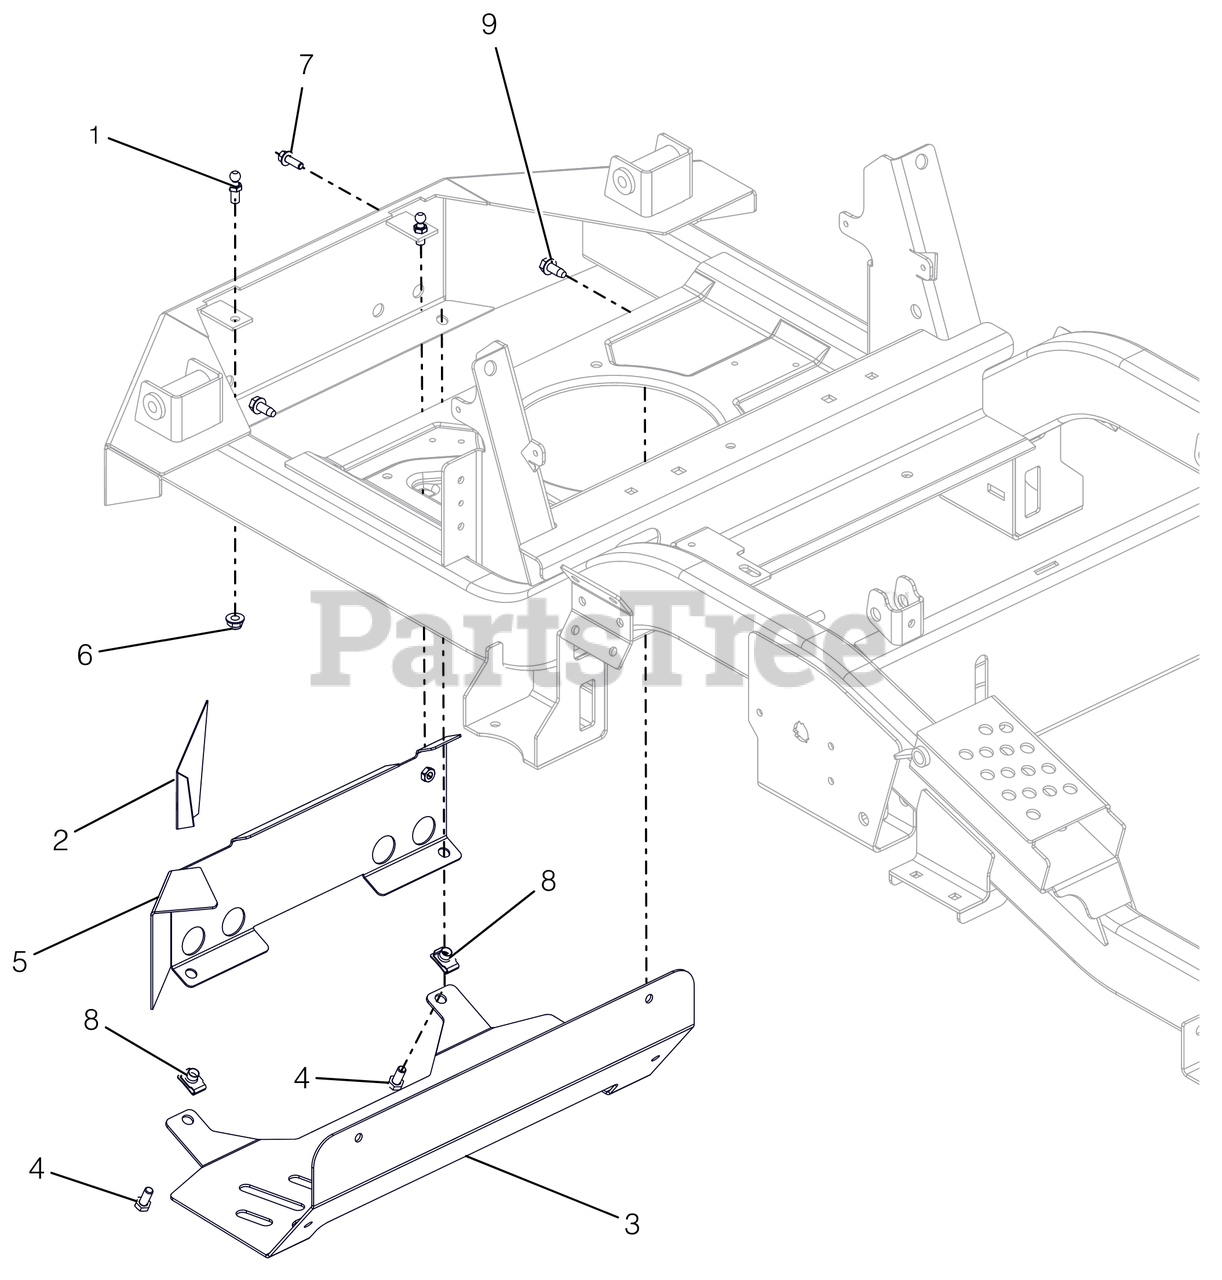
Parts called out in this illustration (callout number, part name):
1	STUD- BALL
2	TAPE, HEAT DEFLECTOR
3	SHIELD, HEAT (HD)
4	@BLT-HEX .31-18X.75 GR5 YWZC
5	WMT, HEAT BAFFLE
6	NUT,LK-NYL-FLG .31-18 G5ZC120
7	BLT,HEX-FLG .25-20X.75 G5 BFP
8	NUT-CLIP RETAINER 5/16-18X.56
9	@SCR-TAP .31-18X.75 HWH TR YWZ
